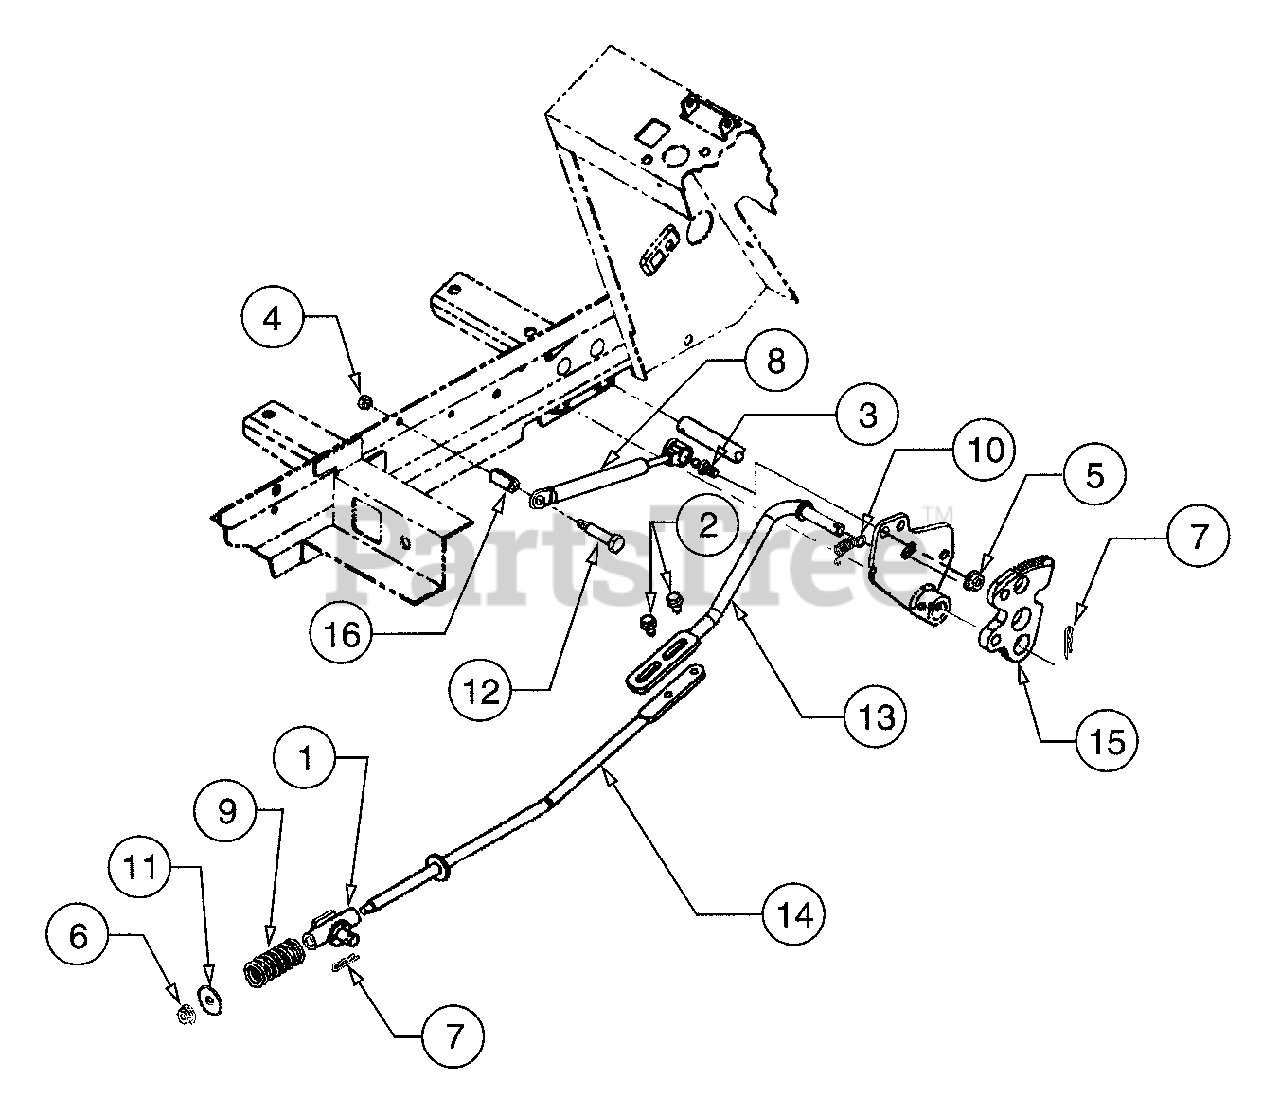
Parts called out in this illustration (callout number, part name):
1	Pivot Assembly
2	Screw, Hex Wsh Hd Tapp, 1/4-20 x .5
3	Screw, Ball, 5/16-18 x.56
4	Nut, Hex Sems, 1/4-20
5	Nut, Hex Flange Lock, 5/16-18 GR5
6	Nut, Hex Flange Lock, 1/4-20
7	Pin, Internal Cotter
8	Cylinder, Damper
9	Spring, Compression, .63 ID x 2
10	Spring, Extension, 3/8 OD x 1.44
11	Washer, Flat, .265 x 1 x .030
12	Bolt, Shoulder, .374 Dia x 1.375
13	Rod, Front Control
14	Rod, Rear Hydro Control
15	Plate, Cruise
16	Spacer, Split Tubing, .375 ID x 1.04
